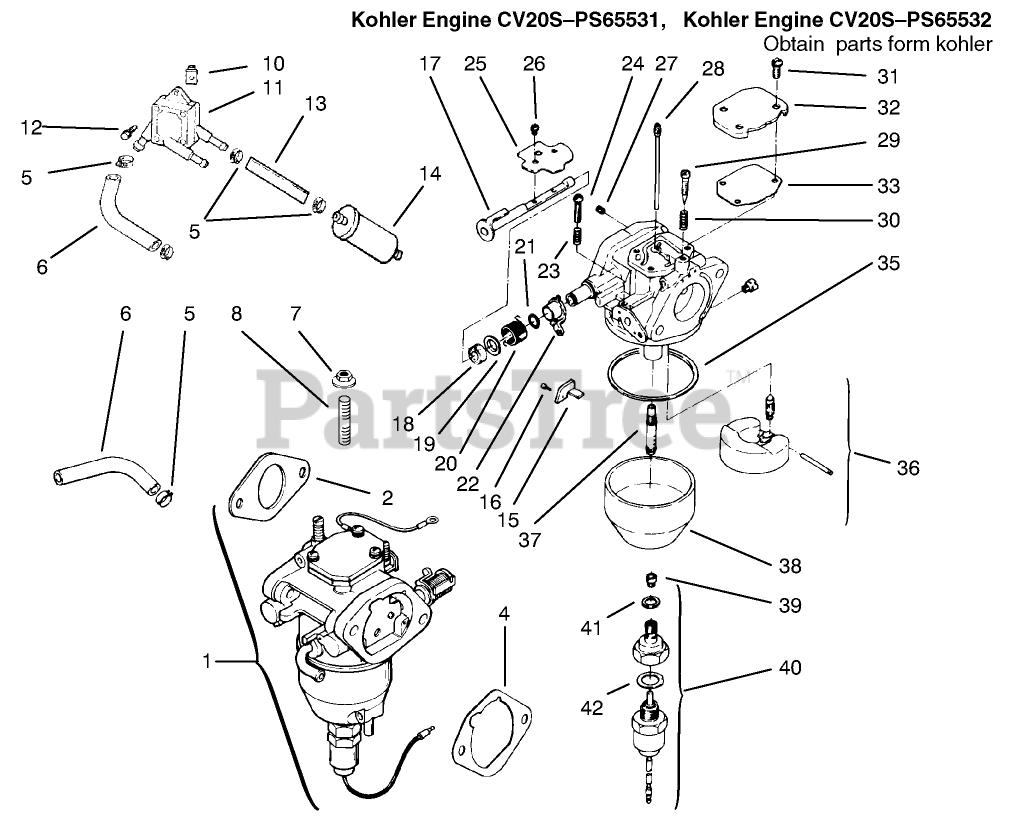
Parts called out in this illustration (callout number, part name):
1	Kit-Carb INC2/4/15-42
2	Gasket-Carburetor (Only On: 72103)
4	Gasket-A/C Base (Only On: 72103, 72083)
5	Clamp
6	Line-Fuel 10 1/2" (Only On: 72103, 72083)
8	Stud M6x1.0x95 (Only On: 72103, 72083)
9	Line-Fuel 12" (Only On: 72103)
11	Pump-Fuel
13	Line-Fuel 3 1/2" (Only On: 72103)
14	Filter-Fuel (Only On: 72042,72043,72062,72063)
15	Bracket-Throttle Stop (Only On: 72103, 72083)
16	Screw M2.5X45X5.5 (Only On: 72103)
17	Shaft-Choke (Only On: 72103, 72083)
18	Washer (Only On: 72103, 72083)
19	Collar-Choke (Only On: 72103, 72083)
20	Spring-Choke Return (Only On: 72103, 72083)
21	Ring-Choke Lever (Only On: 72103)
22	Lever-Choke (Only On: 72103)
23	Spring-Throttle Screw (Only On: 72103, 72083)
24	Screw-Throttle Adjust (Only On: 72103, 72083)
25	Valve-Choke (Only On: 72103)
26	Screw-Throttle Shaft (Only On: 72103, 72083)
27	Jet-Air Bleed (Only On: 72103)
28	Jet-Slow (Only On: 72103)
29	Screw-Idle Adjust (Only On: 72103, 72083)
30	Spring-Idle Adjust Screw (Only On: 72103)
31	Screw (Only On: 72103)
32	Cover-Passage (Only On: 72103, 72083)
33	Gasket-Passage Cover (Only On: 72103, 72083)
35	Gasket-Float Chamber (Only On: 72103)
36	Kit-Float Repair (Only On: 72103)
37	Nozzle-Main (Only On: 72103,72083)
38	Chamber-Float (Only On: 72103)
39	Jet-Main (Only On: 72103)
40	Kit-Solenoid INC 41-42 (Only On: 72103, 72083)
41	Gasket-Chamber Screw (Only On: 72103)
42	Gasket-Solenoid (Only On: 72103, 72083)
